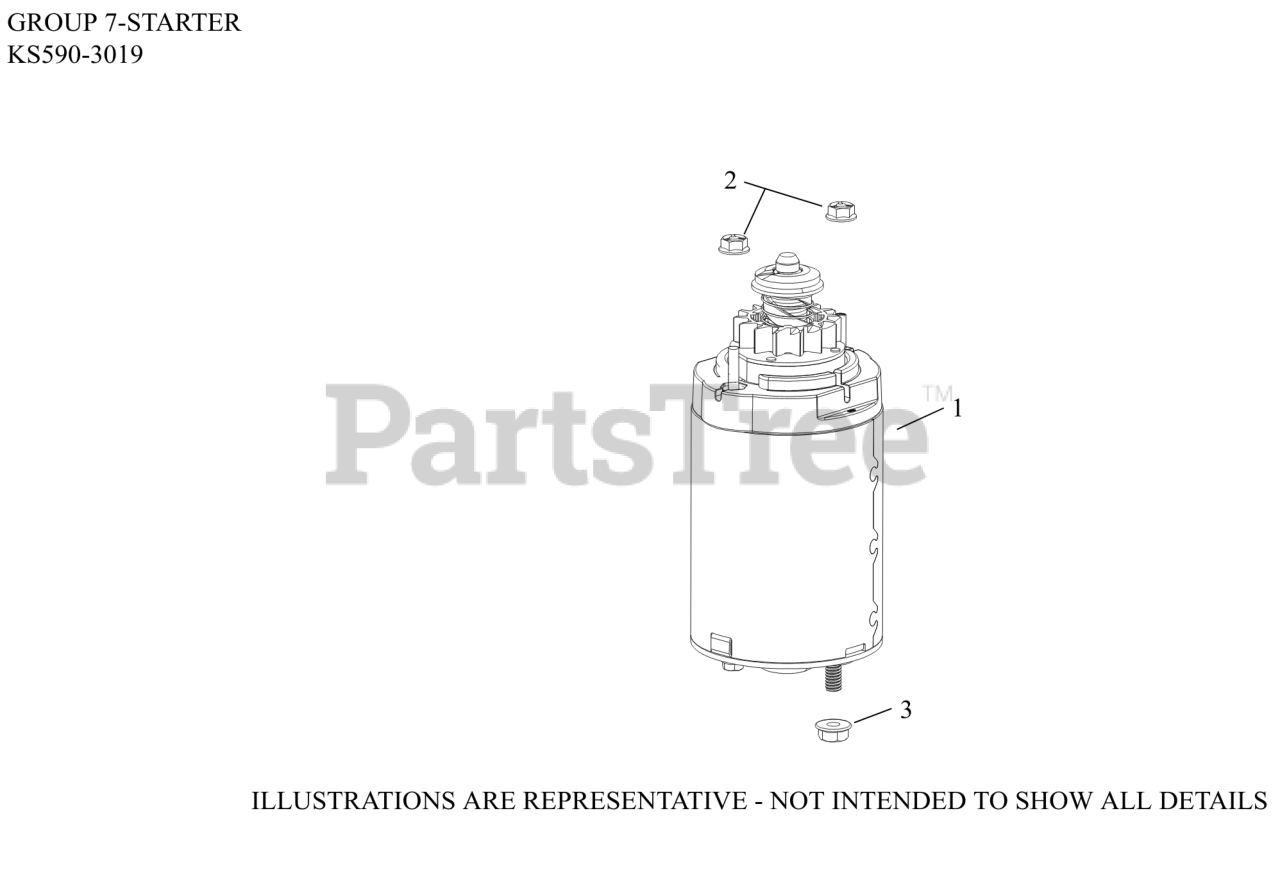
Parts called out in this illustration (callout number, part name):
1	STARTER, ASSY
2	NUT, HEX FLANGE LOCK (10-24)
3	NUT, FLANGE 1/4-20
